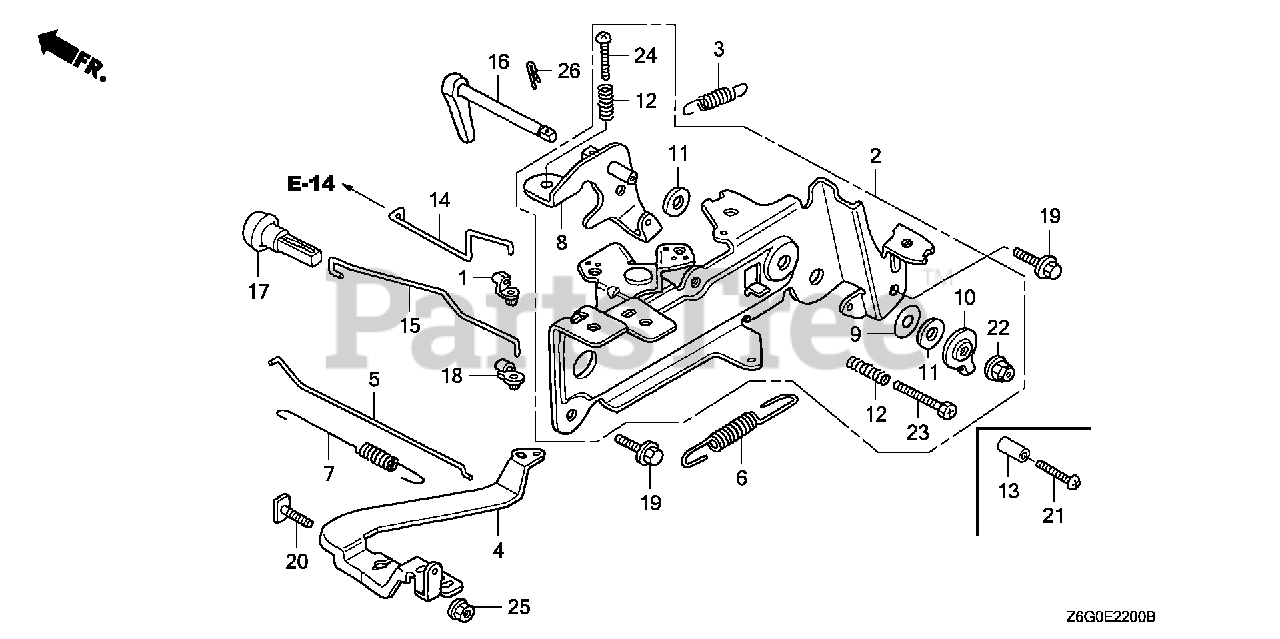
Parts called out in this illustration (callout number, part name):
1	JOINT, ROD
2	CONTROL ASSY.
3	SPRING, STARTER
4	ARM, GOVERNOR
5	ROD, GOVERNOR
6	SPRING, GOVERNOR (MANUAL)
7	SPRING, THROTTLE RETURN
8	ARM, CONTROL
9	SPRING, LEVER
10	WASHER, CONTROL ARM
11	SPACER, CONTROL LEVER
12	SPRING, CONTROL ADJUSTING
14	ROD, CHOKE CONTROL
15	ROD, CHOKE KNOB
16	LEVER ASSY., THROTTLE
17	KNOB, CHOKE
18	BUSH, LINKAGE
19	BOLT, FLANGE (6X14) (CT200)
20	BOLT, GOVERNOR ARM
22	NUT, SELF-LOCK (6MM)
23	BOLT, RECESSED (5X25)
24	SCREW, PAN (5X25)
25	NUT, FLANGE (6MM)
26	PIN, LOCK (10MM)
